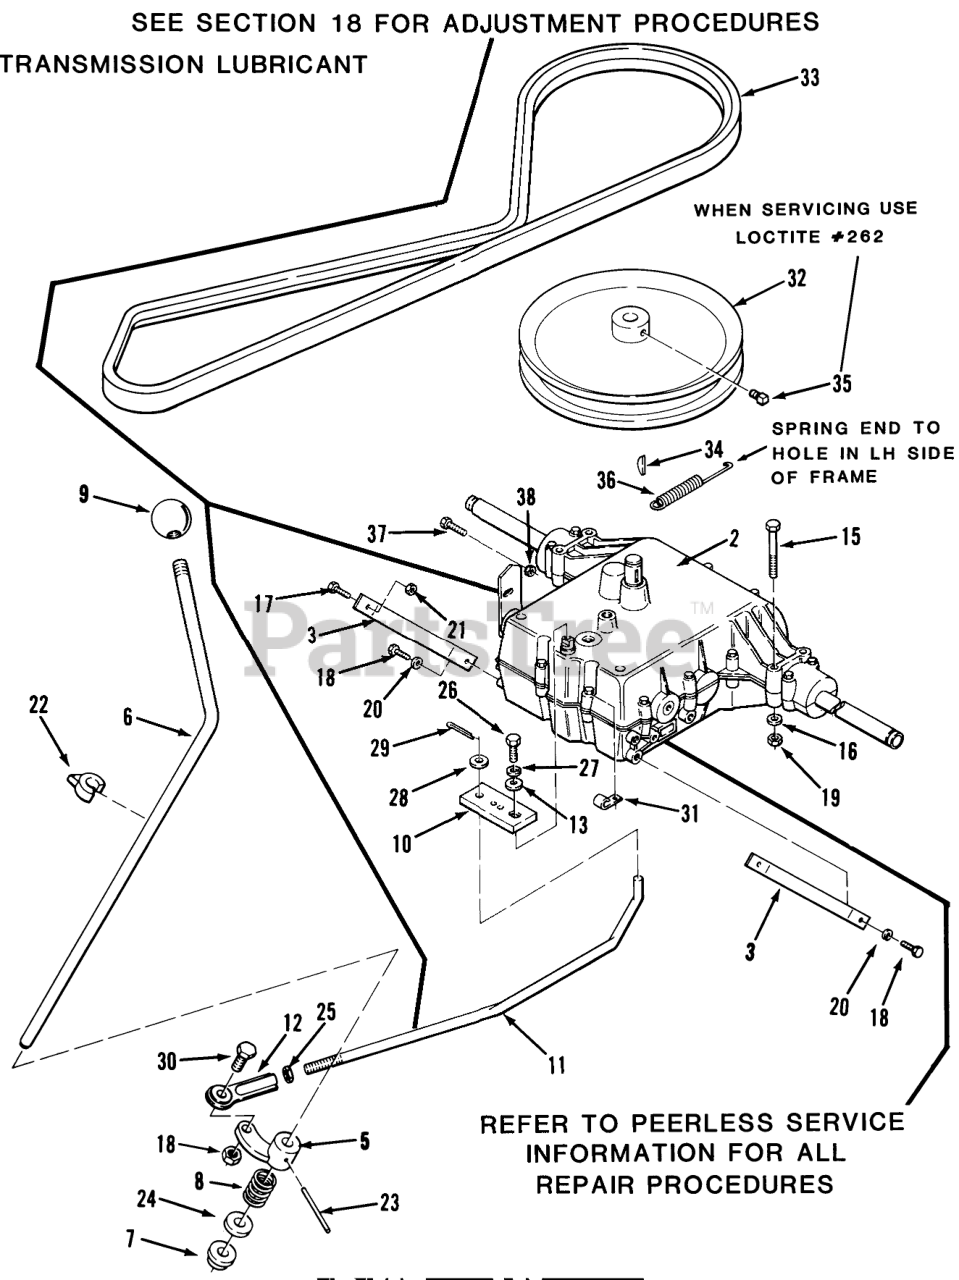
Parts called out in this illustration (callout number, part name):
2	4-Speed Transmission (Peerless Model 920-028)
2	Trans.-5-Spd.(Peerless Model 920-009)
5	ARM SHIFTER *B
6	ROD-SHIFT LEVER
7	BUSHING-NYLINER
8	SPRING COMPRESSION
11	ROD-LINKAGE
13	WASHER
16	WASHER 5/16 SAE
17	CARRIAGE BOLT -4
18	Screw
22	POINTER
23	SPIROL PIN 7/32X21/2
24	Washer
24	WASHER
28	WASHER 5/16 SAE
31	J-CLIP
33	BELT-V
34	KEY-HI-PRO
36	SPRING-EXTENSION
